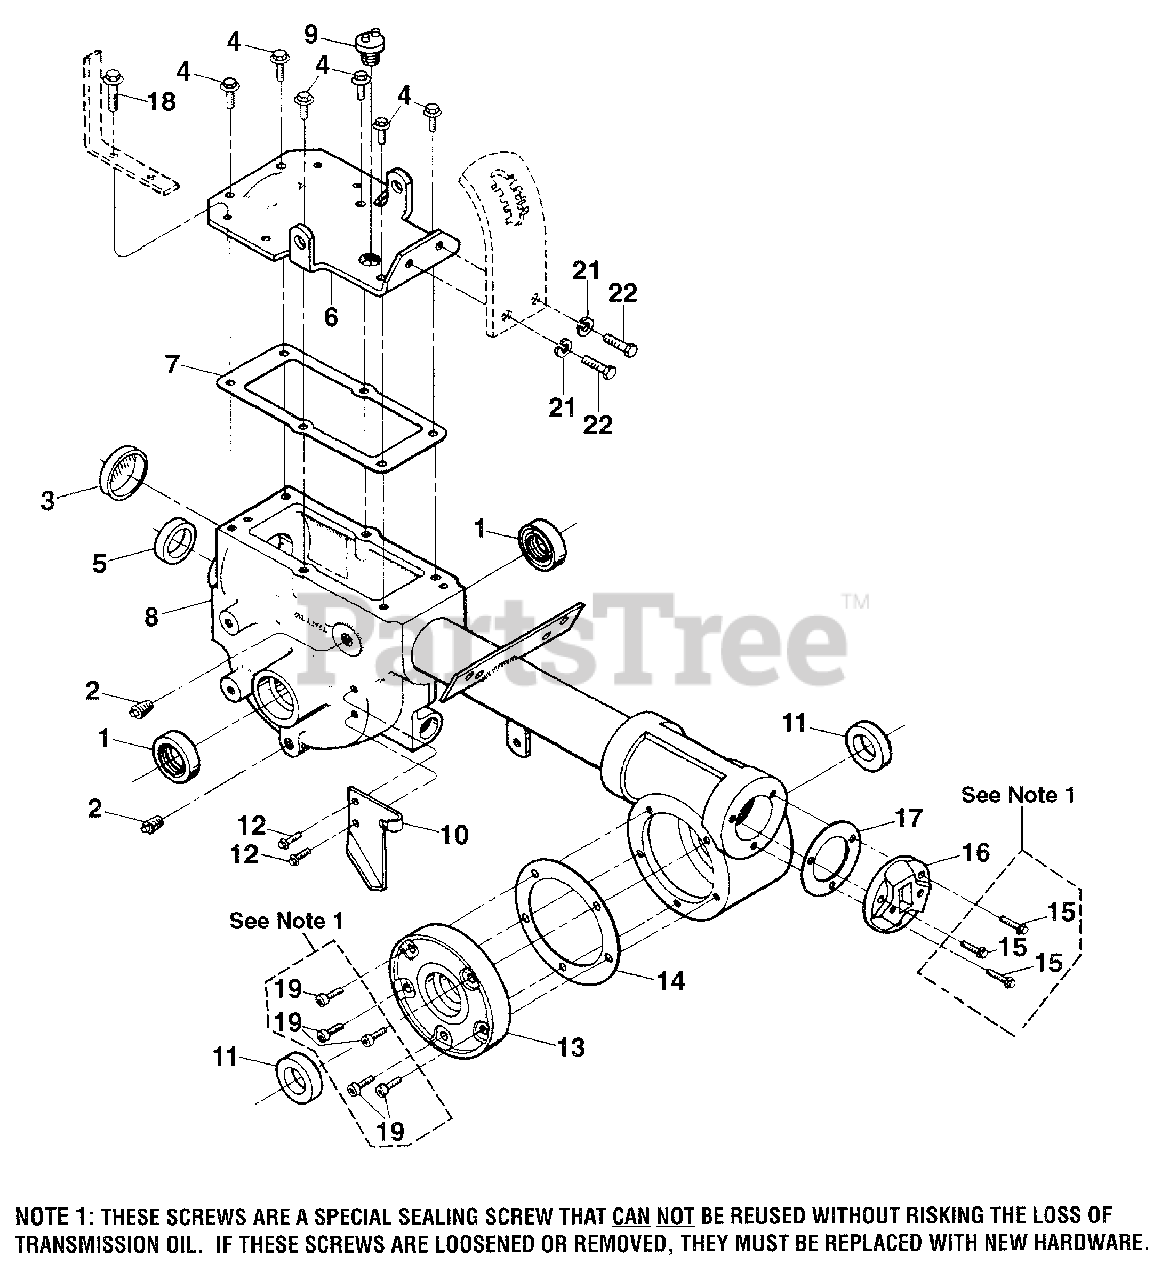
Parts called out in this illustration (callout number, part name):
1	Oil Seal-double lip, wheel shaft, right and left sides
2	Plug-pipe, 1/4, oil level hole and gear oil drain hole
3	Seal-transmission bore
4	Screw-flanged hex hd., 5/16-18 x 3/4
5	Oil Seal-input pinion shaft
6	Cover-top of transmission
7	Gasket-transmission top cover
8	Transmission case, tube and rear housing assembly
9	Plug-gear oil fill hole
10	Plate-wheel drive cable mounting
11	Oil Seal-tiller shaft, left and right sides
12	Screw-flanged hex hd., 5/16-18 x 5/8
13	Cover-tiller housing, left side
14	Gasket-tiller housing cover, .010 (fits all covers)
15	Screw Kit:
16	Cap-rear bearing
17	Gasket-rear bearing cap, .010 thick
18	Screw-flanged hex hd., 5/16-18 x 1
19	Screw Kit:
21	Lockwasher-3/8
22	Screw-hex hd., 3/8-16 x 3/4
